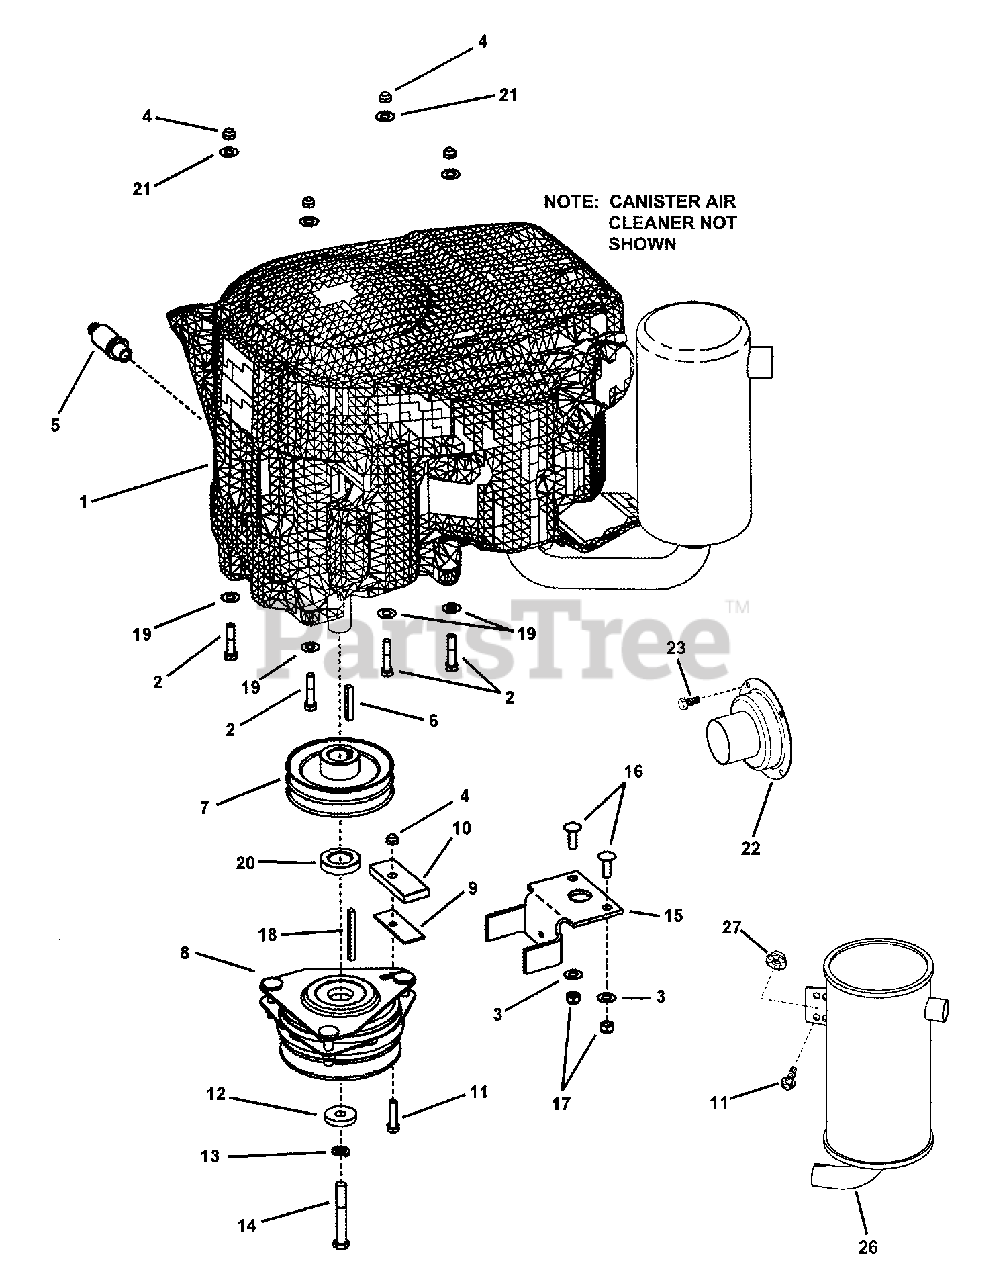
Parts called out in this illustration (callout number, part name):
2	SCREW, 5/16-18 x 1-1/2" Hex Head Cap, GR 5
3	RETAINER, 3/8" Bolt
4	NUT, 5/16-18 Hex Top Lock GR B
5	ASSEMBLY, Oil Valve
6	KEY, 1/4" Square x 3/4"
7	PULLEY, 4.26 x 1.375 OAL x 1" Bore
8	CLUTCH, Electric (Ogura Model # GT2.5-RM01)
9	WASHER, Rectangular Steel
10	BUMPER, Electric Clutch
11	BOLT, 5/16-18 X 1-1/4 GD5 YZ
12	WASHER, .468 x 1.85 x .25 Flat
13	WASHER, 7/16" Split Lock
14	SCREW, 7/16-20 x 2-1/2" Hex Head Cap, GR 5
15	BRACKET, Clutch
16	BOLT, 3/8-16 x 1" Square Neck Carriage GR 5
17	NUT, 3/8-16 HEX NYLON LOCK
18	KEY, 1/4" Square x 2-1/4" Long
19	RETAINER, 5/16" Bolt
20	SPACER, Clutch
21	WASHER, 5/16" Flat
22	OUTLET, Muffler
23	SCREW, #8-18 x 1/2" Hex Washer Self-Tap
26	MUFFLER
27	NUT, 5/16-18 Hex Flange Lock
